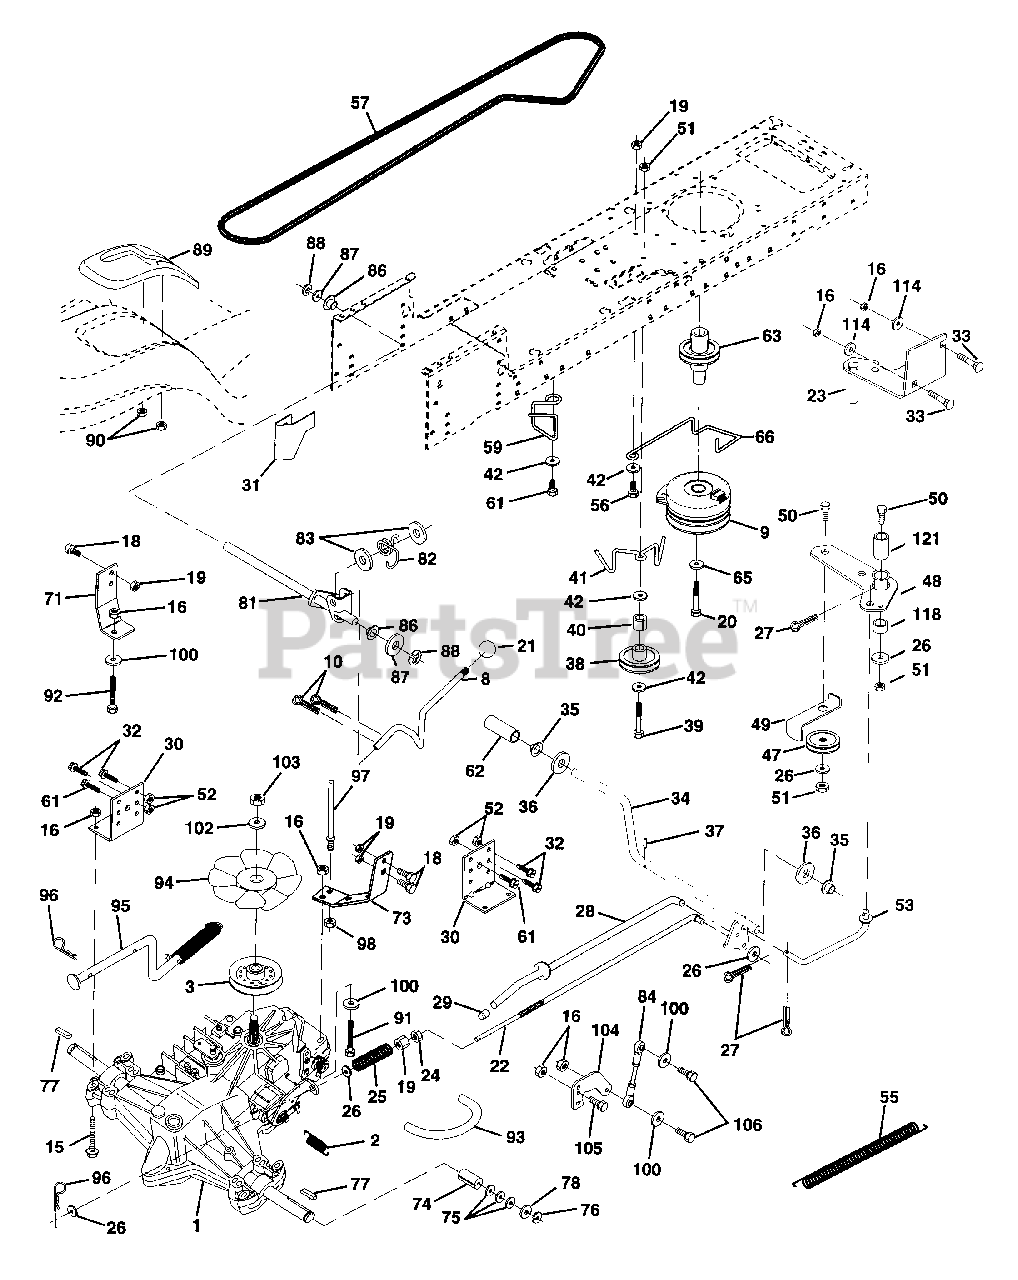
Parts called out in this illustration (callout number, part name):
1	Transaxle w/cas Hydro 310-0650
2	Spring, Return, Brake
3	Pulley, Transaxle Hydro 750 LT
8	Rod Shift Hydro LT
9	Clutch Electric
10	Pin Cotter 1/8 x 1 CAD
15	Bolt Hex 5/16-18 Unc Flghd
16	Nut Lock Hex W/Ins. 5/16-18 Unc P
18	Bolt Fin Hex 3/8-16 Unc x 1 Gr.5
19	Nut Lock Hex W/Ins 3/8-16 Unc
20	Bolt, Hex 7/16-20 x 4-1/4 Ga. 5
21	Knob Deluxe 1/2-13 UNC BLK/BLK
22	Rod, Brake Hydro
23	Bracket Asm Mtg CL
24	Nut Hex Jam 3/8-16 UNC
25	Spring, Brake Rod
26	Washer
27	Pin Cotter 1/8 x 3/4 CAD.
28	Rod, Parking Brake
29	Cap,Parking Brake
30	Bracket, Transaxle
31	Keeper Belt Lh
32	Bolt Hex Hd 5/16-18 Unc x 3/4
33	Bolt Carriage 5/16-18 UNC x 3/4
34	Shaft, Foot Pedal
35	Bearing, Nylon
36	Washer
37	Pin, Roll
38	Pulley, Idler, Flat
40	Spacer Split
41	Keeper, Belt Idler
42	Washer 13/32x13/16x12Ga
47	Pulley, Idler, V-Groove Plastic
48	Bellcrank Assembly
49	Retainer, Belt Style Spring
50	Bolt
52	Nut Crown Lock 5/16-18
53	Link, Clutch
55	Spring, Return, Clutch
56	Bolt, Fin Hex 3/8-16 UNC x 1 1/4
57	V-Belt, Ground Drive
59	Keeper, Center Span
61	Screw Thdrol. 3/8-16 x 3/4 Ty. TT
62	Cover, Pedal Premium
63	Pulley, Engine
65	Washer Lock Hvy HLCL Spr 7/16
66	Keeper Belt Engine
71	Strap Torque Lh Hydro
73	Strap Torque Rh Hydro
74	Spacer, Split
75	Washer 25/32 x 1-1/4 x 16 Ga.
77	Key, Square
78	Washer 25/32 x 1-5/8 x 16 Ga
81	Shaft Asm. Cross Hydro 20" Tires
82	Spring Torsion T/A
83	Washer 17/32 x 3/4 x 16 Ga.
84	Rod, Tie Hydro 20" Tires SPH Ball 4.75
86	Bushing Rod Strig. 629/632 ID
87	Washer 21/32 x 1-1/4 x 16 Ga.
88	Ring Klip #5304-62
89	Console, Hydro STLT
90	Nut Self-Thd Wsh-Hd 1/4 Zinc
91	Bolt Fin Hex 5/16-18 x 2-1/4
92	Bolt Fin Hex 5/16-18 Unc x 1-1/2
93	Line Fuel Hydro 4"
94	Fan, Hydro 7"
95	Control Asm. Bypass Hydro
96	Retainer Spring 1" Zinc/Cad
97	Keeper Belt Rh Hydro 0750.18/20"
98	Nut Keps Hex 3/8-16 Unc
100	Washer 11/32 x 3/4 x 16 Ga.
102	Washer Belleville .501D x 1.50D
103	Nut Hex Jam Toplock 1/4-20 Unf
104	Arm, Control Hydro
105	Screw Cap Hex 5/16 x 18 x 1
106	Bolt Fin Hex 5/16-18 Unc x 1-1/4
114	Washer 11/32 x 3/4 x 14 Ga.
118	Spacer Bellcrank
121	Nyliner Clutching STL
